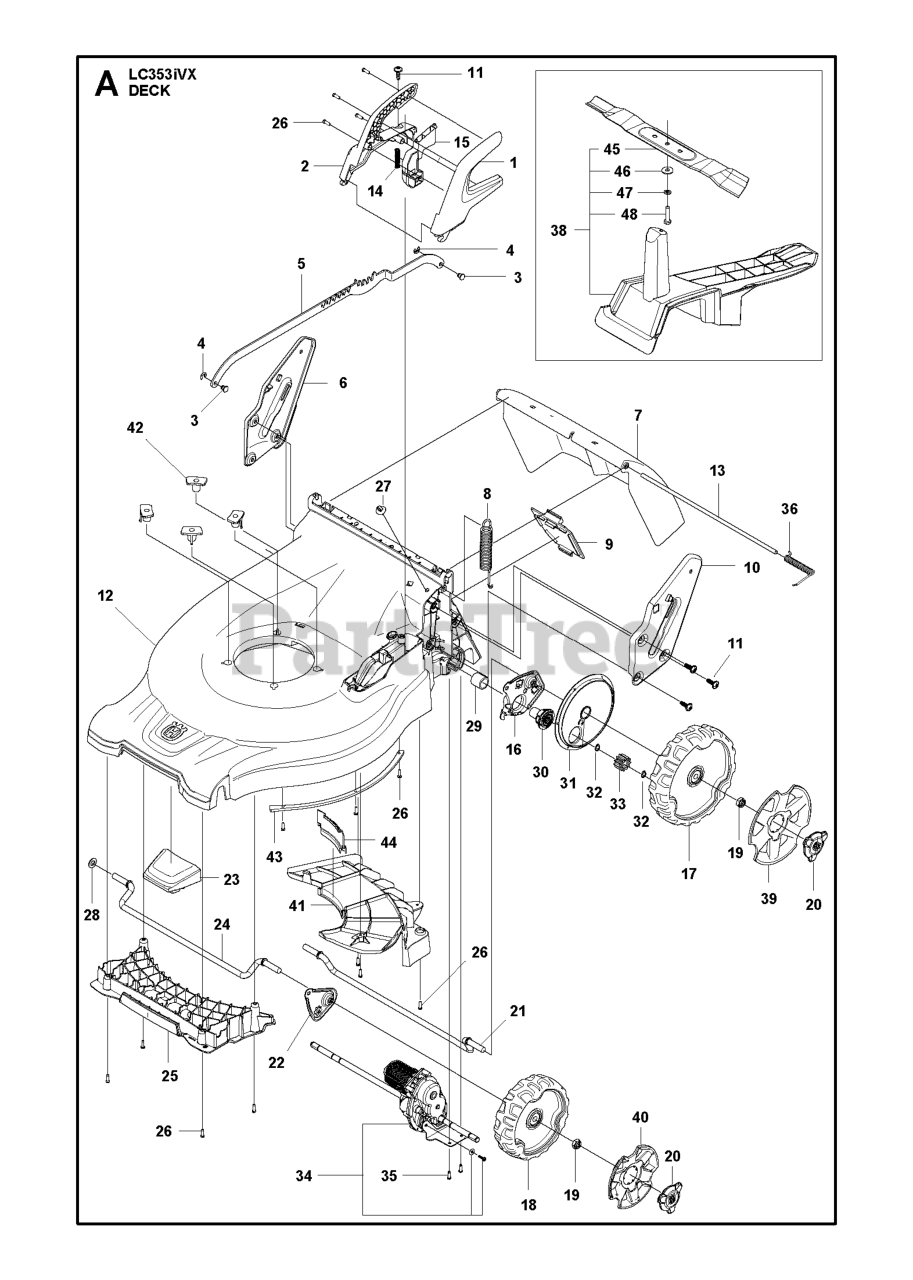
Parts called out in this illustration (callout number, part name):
4	Retaining Ring
20	NUT CAP
26	SCREW ITXPANT T50X16 ZN/FE (A
28	Washers
33	Pinions
35	SCREW ITXPANT T50X16 ZN/FE (A
46	SPACER
47	SPRING WASHER
48	SCREW
